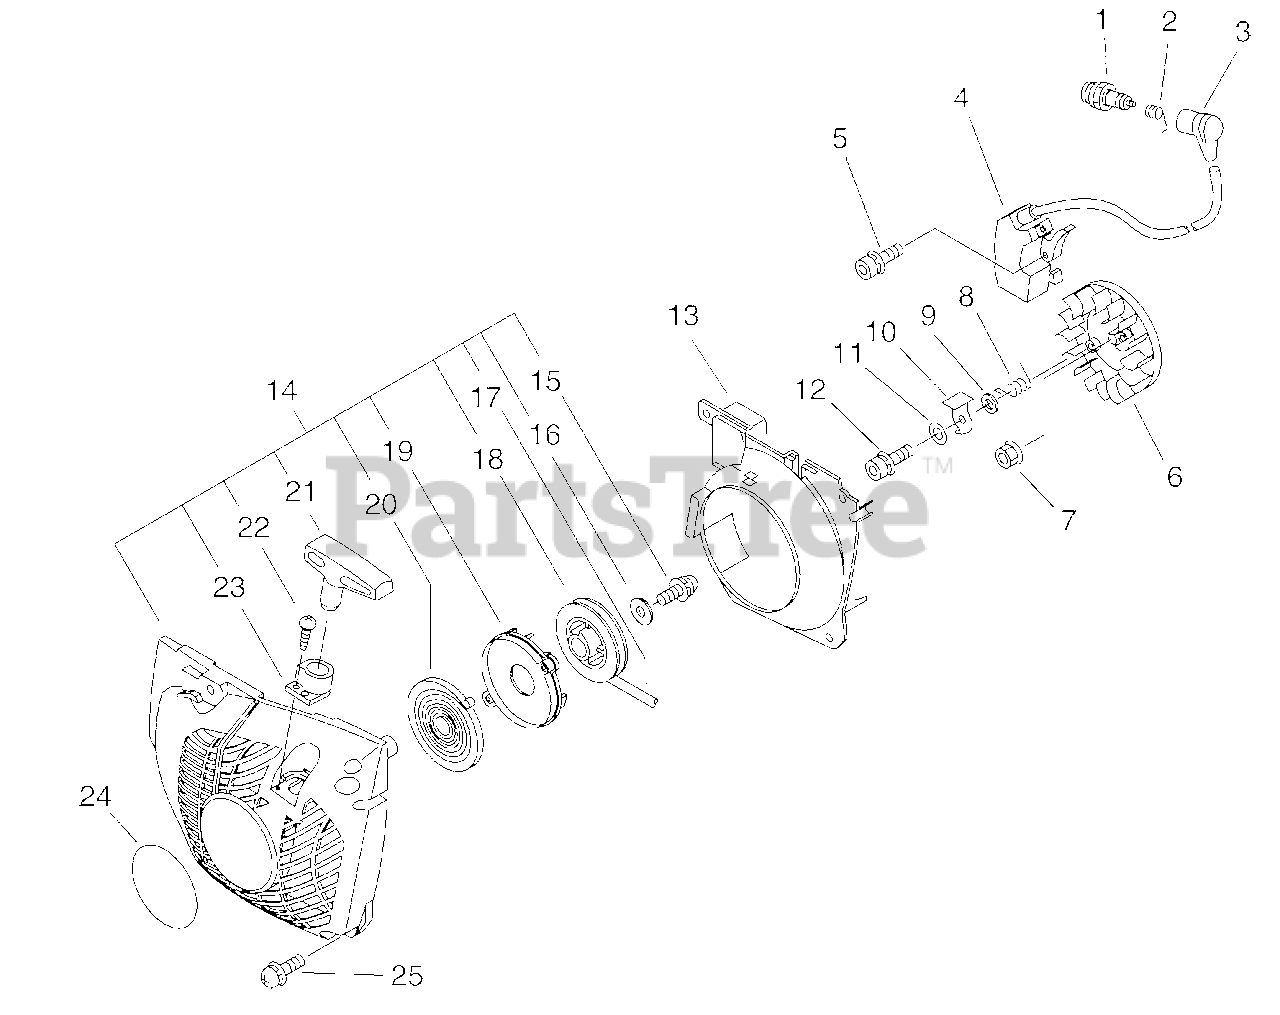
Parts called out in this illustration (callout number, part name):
1	SPARK PLUG - BPM8Y
2	TERMINAL, SPARK PLUG
3	CAP, SPARK PLUG
4	COIL, IGNITION
5	BOLT 4×30
6	FLYWHEEL
7	NUT, FLANGE M8
8	SPRING, TORSION
9	WASHER 5.5×12×0.8
10	PAWL, STARTER
11	SPACER 5.2×8×2.1
12	BOLT 5×14
13	COVER, FAN
14	STARTER ASSY, RECOIL
15	SCREW 5×12
16	WASHER 5.2×16×1.0
17	ROPE, STARTER
18	REEL, ROPE
19	PLATE, STARTER
20	SPRING, RECOIL
21	GRIP, STARTER
22	SCREW 3×14
23	GUIDE, ROPE
24	LABEL, ECHO
25	SCREW 5×18
